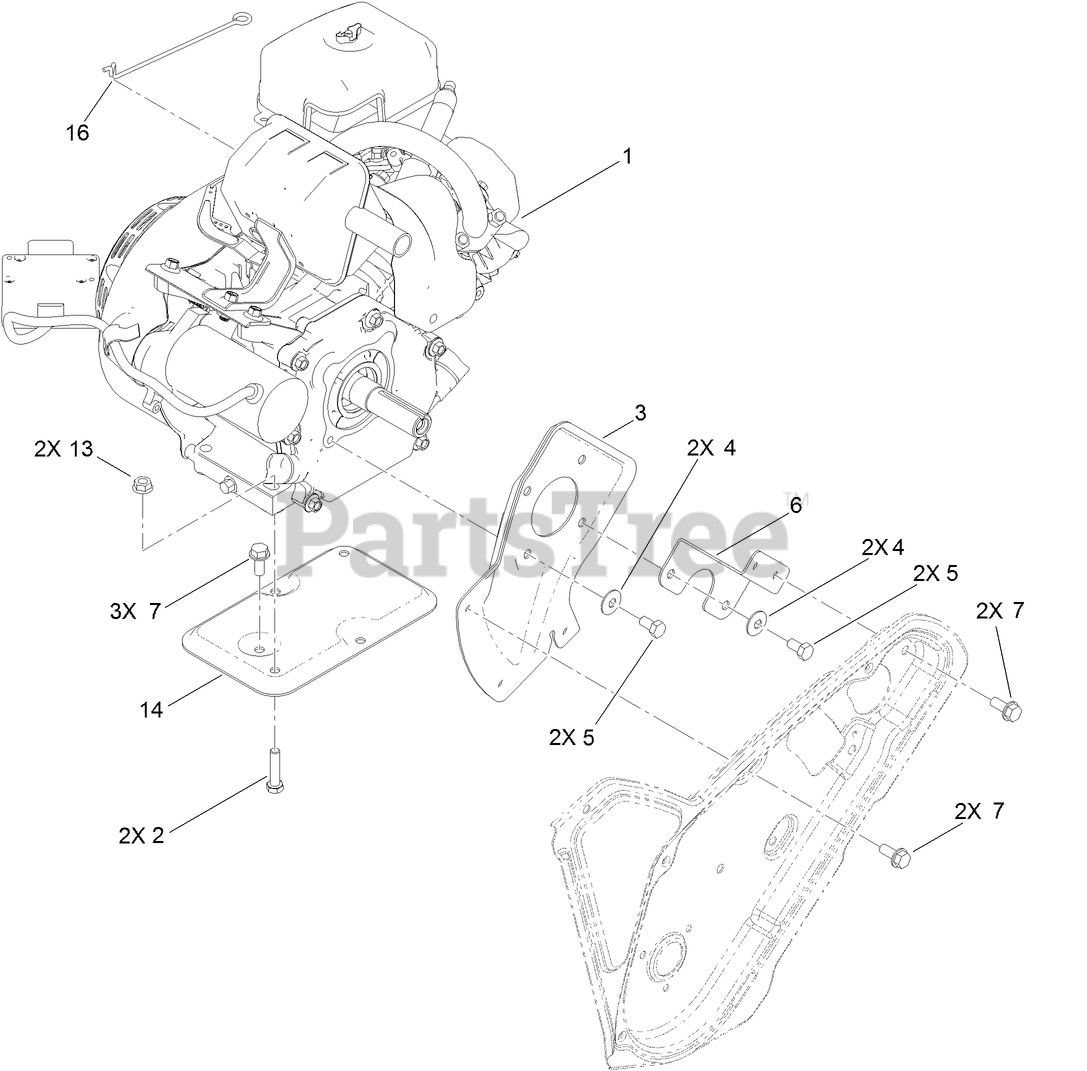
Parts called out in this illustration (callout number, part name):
1	ENGINE-168FDS-1
2	SCREW-HH
3	PLATE-ENGINE, PTO
4	WASHER-BELLEVILLE
5	SCREW-HH
6	SUPPORT-ENGINE, SIDE
7	SCREW-THD ROLL, HWH
13	NUT-HF
14	SUPPORT-ENGINE
